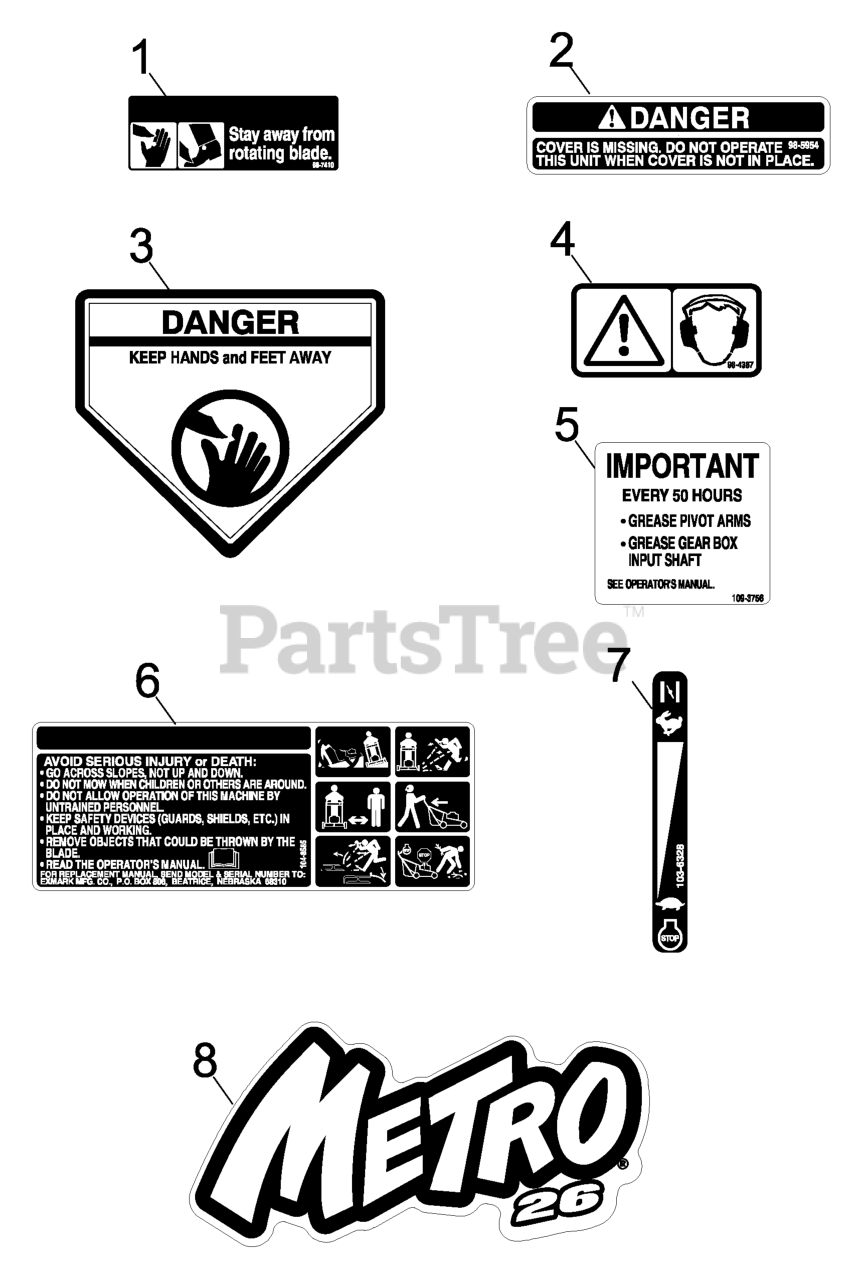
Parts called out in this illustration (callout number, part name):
1	DECAL-BLADE
2	DECAL-COVER, MISSING
3	DECAL-DANGER
4	DECAL-PROTECTION, EAR
5	DECAL,SERVICE M26
6	DECAL-WARNING
7	DECAL-THROTTLE / CHOKE
8	DECAL,METRO 26
